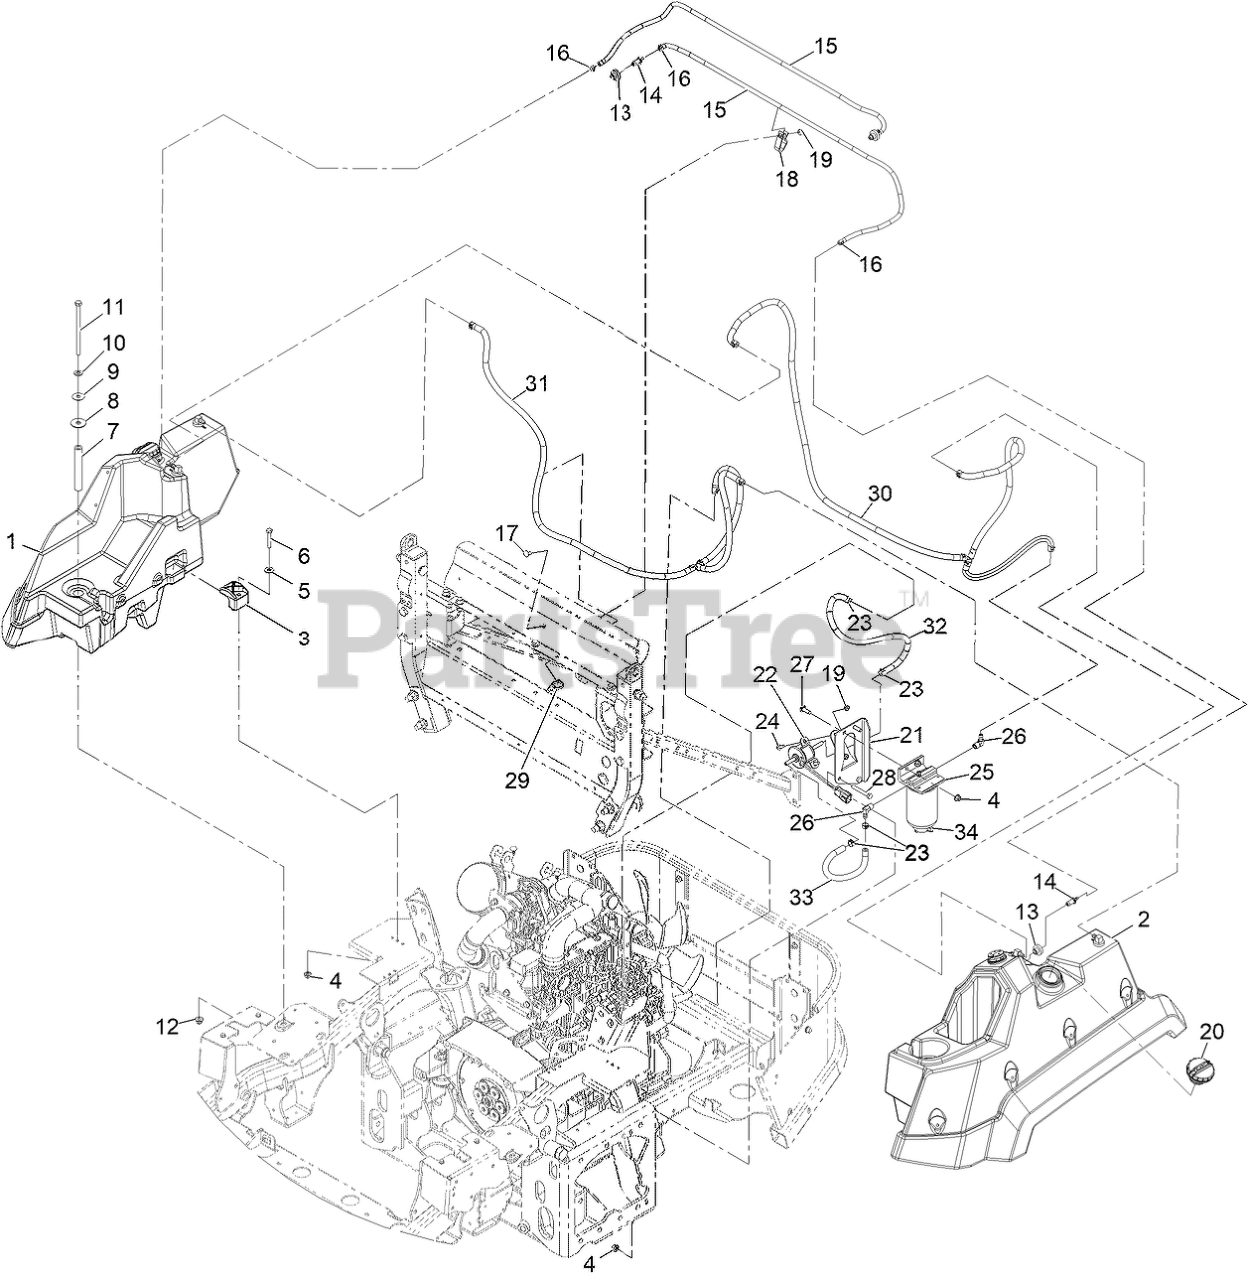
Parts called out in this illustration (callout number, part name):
1	RH FUEL TANK ASM
2	LH FUEL TANK ASM
4	NUT-HF, NI
5	WASHER-FLAT
6	SCREW-HH
7	TUBE-SPACER
8	WASHER-RUBBER
9	WASHER-PLAIN
10	WASHER-FLAT
11	SCREW-HH
12	NUT-HF, NI
13	BUSHING
14	FITTING-ORIFICE, STRAIGHT
15	HOSE-VENT, TANK
16	CLAMP-HOSE
17	SCREW-CARR
18	CLAMP-HOSE
20	CAP-FUEL, DIESEL
21	BRACKET-FILTER AND PUMP,
22	PUMP-FUEL, ELECTRIC
23	CLAMP-HOSE
24	SCREW-HWH
25	ASM,FUEL FILTER W/HEAD
26	FITTING-HYD, 90
27	SCREW-CARR
28	SCREW-HH
29	CLIP-TIE
30	LINE-FUEL, SUCTION
31	LINE-FUEL, RETURN
32	HOSE-FUEL
33	HOSE-FUEL
34	FILTER-FUEL
